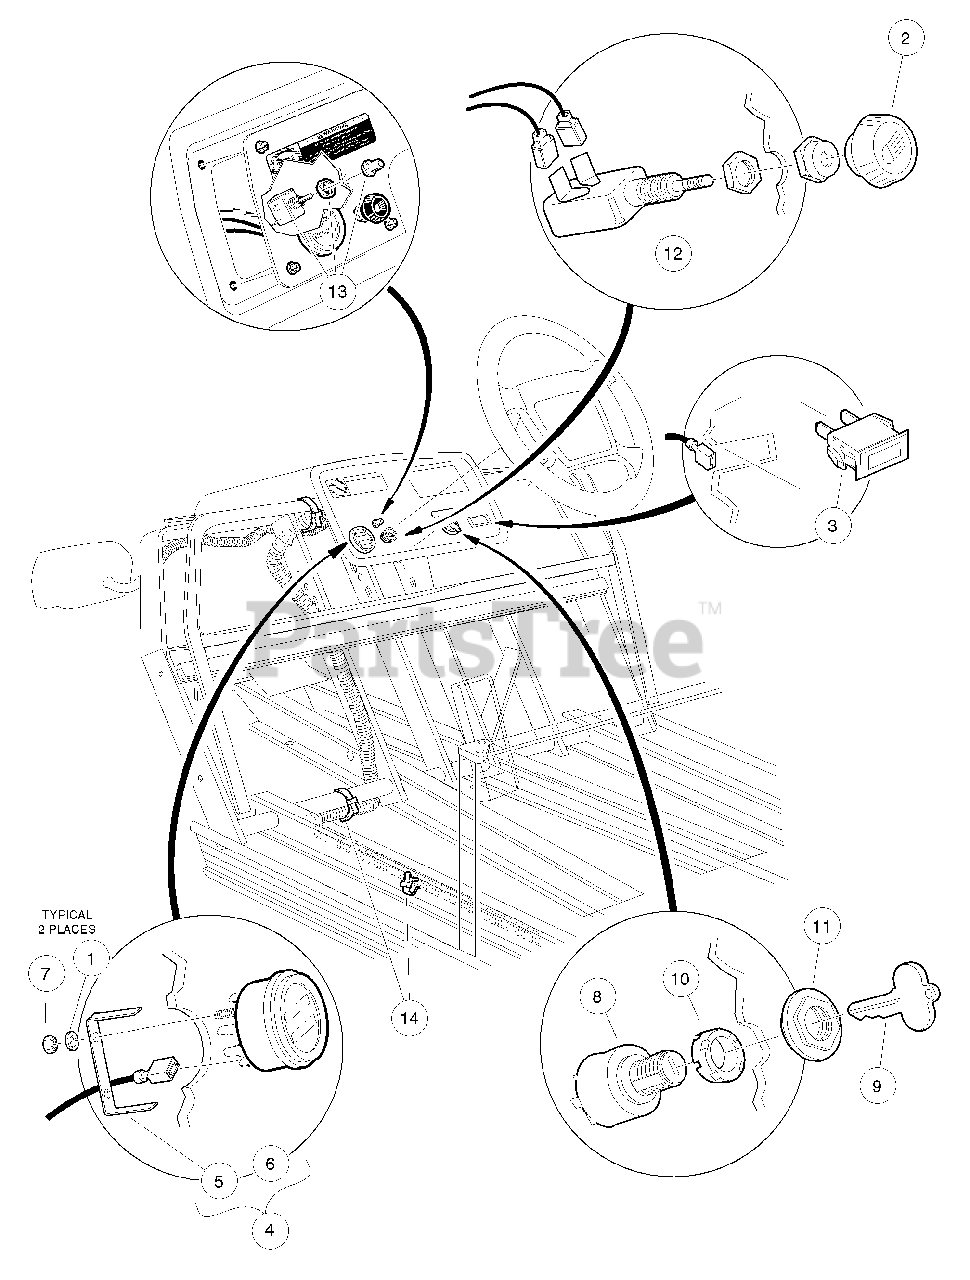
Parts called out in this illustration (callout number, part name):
2	Knob, Light Switch
3	Liqht, Oil
4	Gauge, Fuel/Hour, with Bracket
5	Bracket, Fuel Gauge/Hour Meter
6	Gauge, Fuel/Hour
7	Nut, M4-0.7
8	Key Switch 12v Key Start
10	Spacer, Keyswitch
11	Nut, Key Switch
12	Switch, Light
14	Tie Wrap, 8" Nylon
